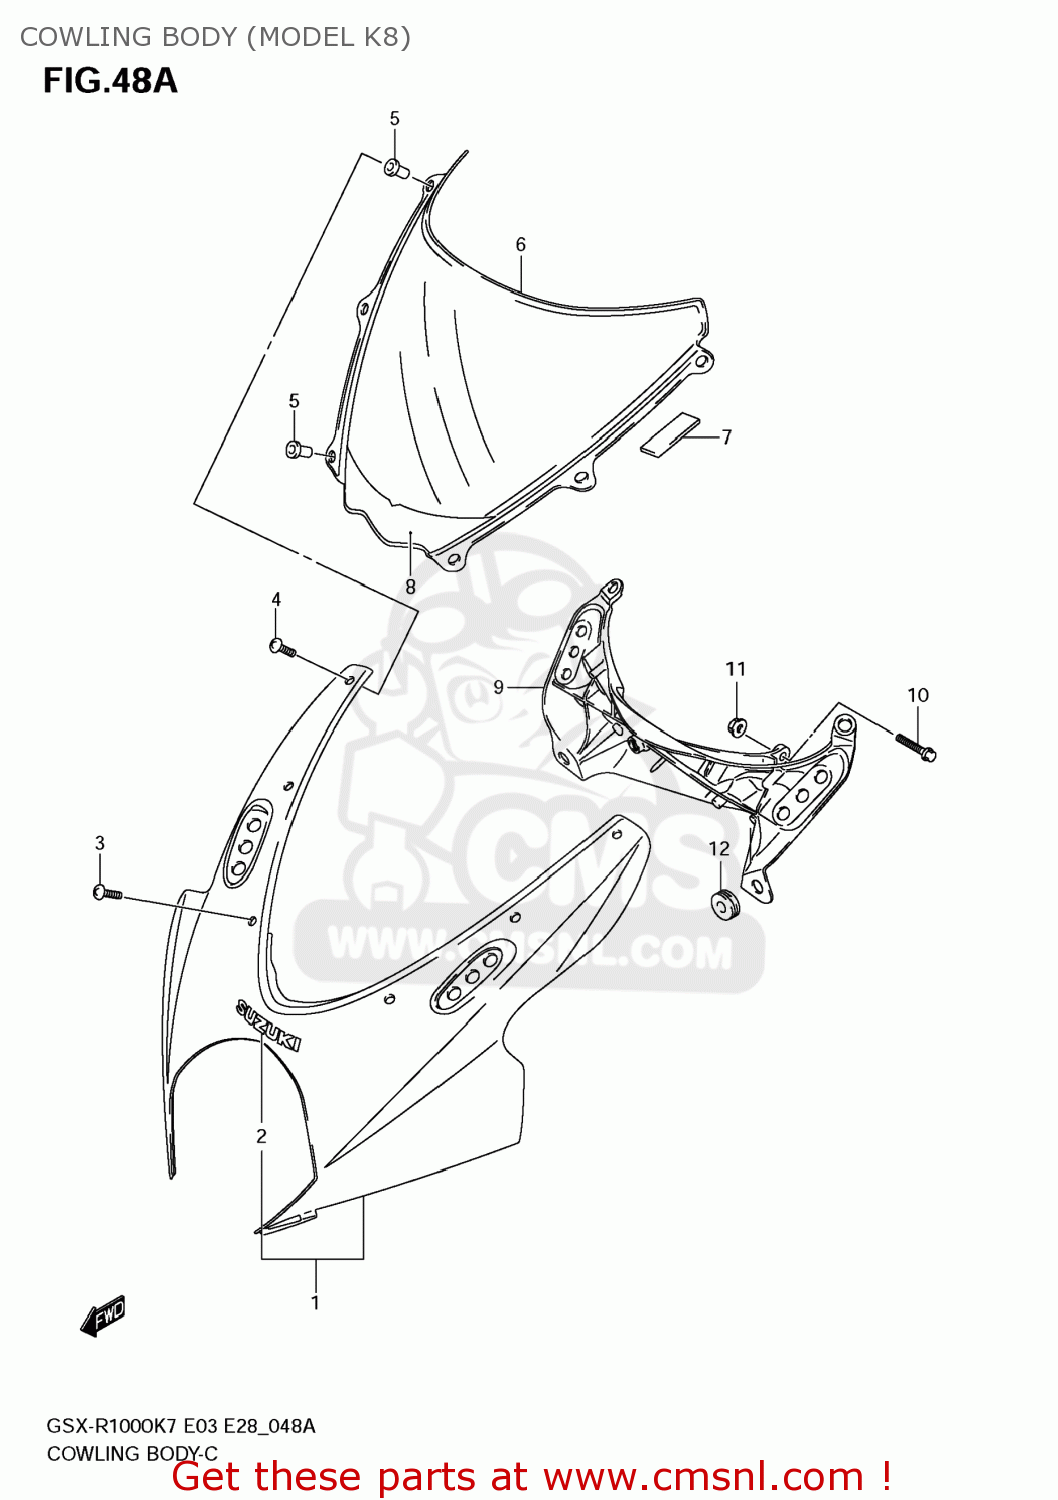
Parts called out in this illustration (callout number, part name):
1	BODY,COWLING(BLUE)
2	EMBLEM,SUZUKI
3	SCREW(5X18)
4	SCREW(5X15)
5	NUT
6	WINDSCREEN
7	TAPE(6X25X0.13)
8	TAPE,SCREEN
9	BRACE,COWLING
10	BOLT
11	NUT
12	CUSHION
